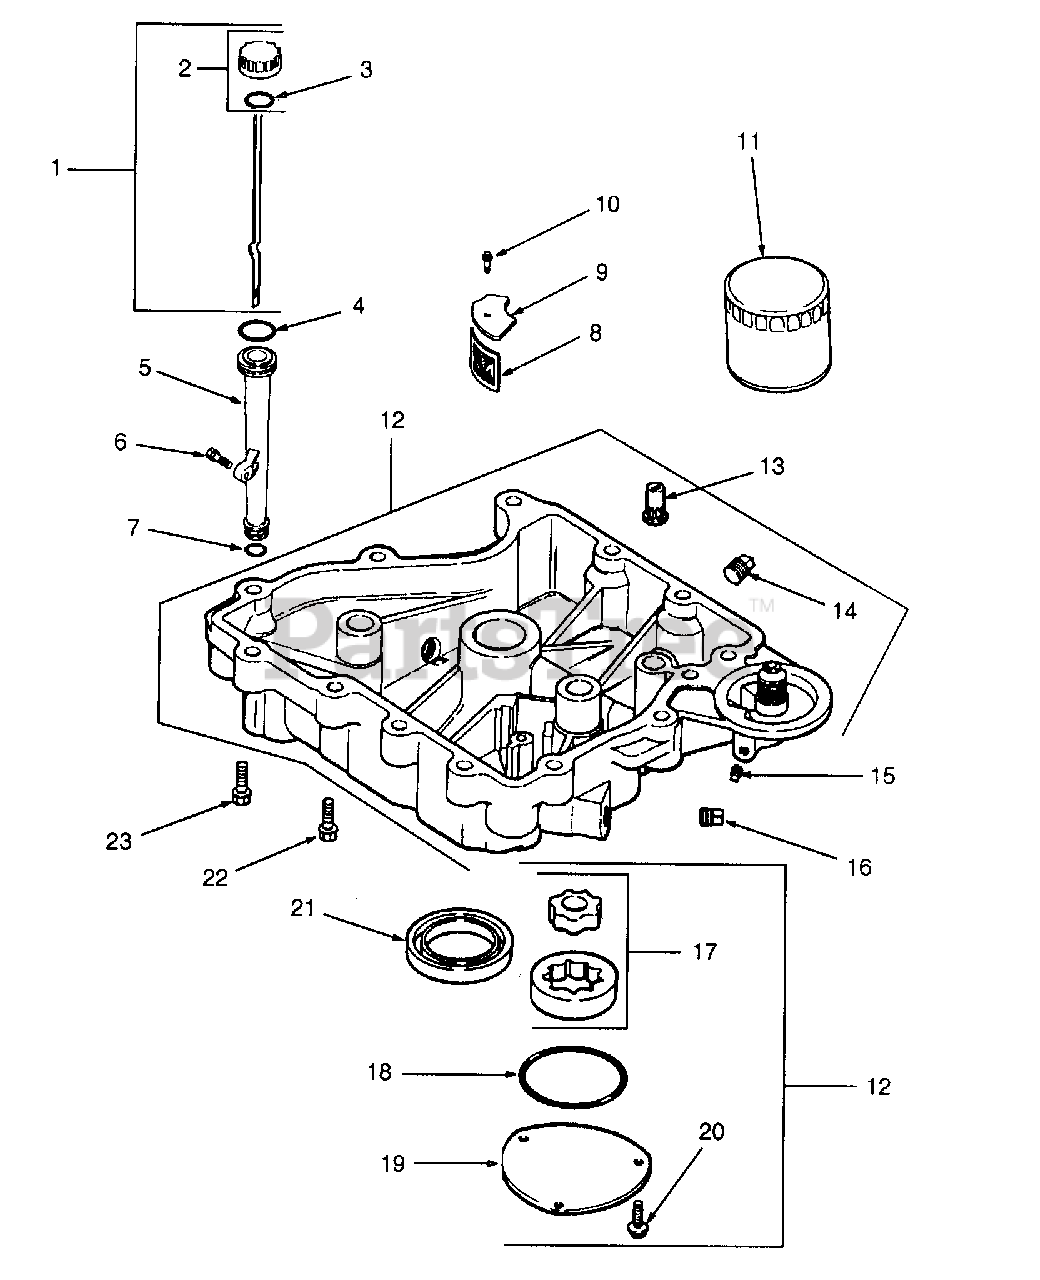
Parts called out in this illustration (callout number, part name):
1	Dipstick Ass'y
2	Cap Kit, Oil Fill
3	O-Ring, Dipstick
4	O-Ring,Upper Oil Fill Tube
5	Tube, Oil Fill
6	Screw, Hex Flange, M5 x 0.8 x 20
7	O-Ring, Lower Oil Fill Tube
9	Cover, Oil Pick-up Screen
10	Screw, Hex Flange, M5 x 0.8 x 16
11	Filter, Oil
12	Pan Ass'y, Oil
13	Valve, Oil Pressure
14	Plug, Pipe 1
15	Plug, Square Hd 1/8
16	Plug, Square Hd 3/8
17	Pump Ass'y, Oil
18	O-Ring, Oil Pump Cover
19	Cover, Oil Pump
20	Screw, Hex Flange, M5 x 0.8 x 16
21	Seal, Oil (PTO End)
22	Screw, Hex Flange, M8 x 1.25 x 45
23	Screw, Hex Flange, M8 x 1.25 x 45
